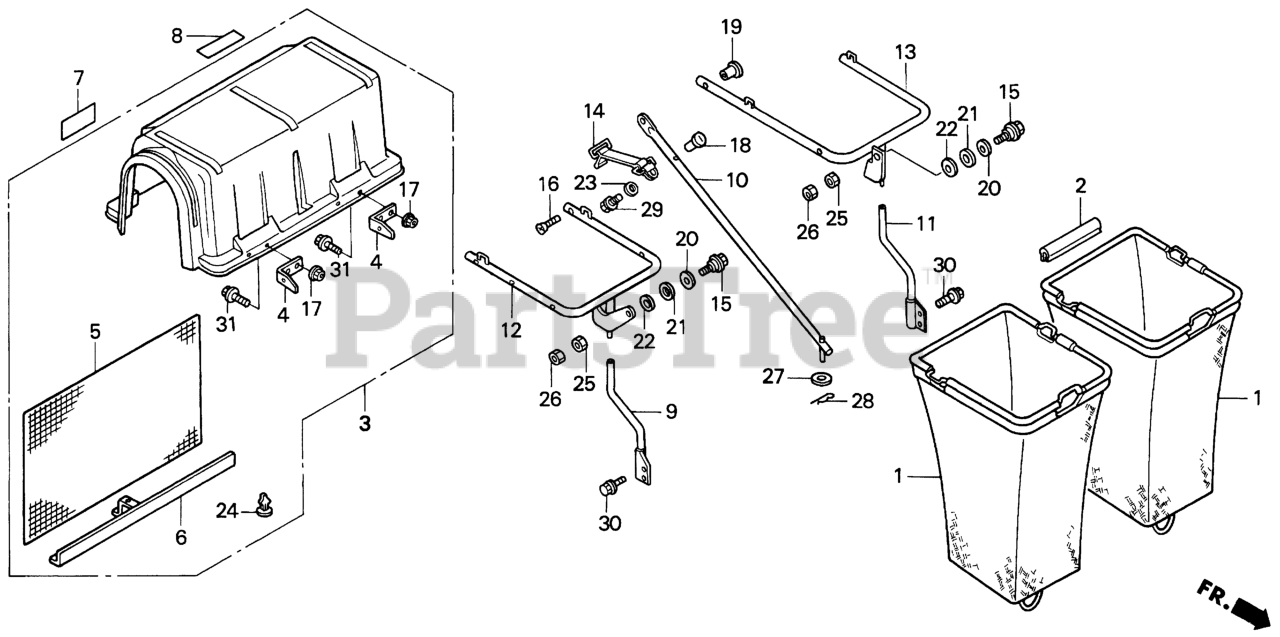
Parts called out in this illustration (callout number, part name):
1	BAG, GRASS
2	CLIP, GRASS BAG TUBE (NOT AVAILABLE)
3	HOPPER ASSY., TOP
4	HINGE, HOPPER TOP
6	STIFFENER, RR. (N/A: SEE ASSEMBLY)
7	LABEL, HOPPER TOP (ENGLISH)
8	LABEL, HOPPER TOP ROOF (ENGLISH)
9	POST, R. SUPPORT
10	BRACE, SUPPORT
11	POST, L. SUPPORT
12	STAY, R. SUPPORT (NOT AVAILABLE)
13	STAY, L. SUPPORT
14	BAND ASSY., HOPPER TOP
15	BOLT, HINGE (10MM)
16	SCREW, FLAT (8X45)
17	NUT, FLANGE (6MM)
18	NUT, PIPE (6MM)
19	NUT, PIPE (8MM)
20	WASHER, THRUST (14MM)
21	WASHER, SPRING (14MM)
22	WASHER (12MM)
23	WASHER (3/8")
24	CLIP, SCREEN
25	NUT, HEX. (10MM) (NOT AVAILABLE)
26	NUT, HEX. (10MM) (SOURCE: VINTAGE PARTS INC.)
27	WASHER, PLAIN (10MM)
28	PIN, LOCK (10MM) Use from Frame SN 2149606 to 2149605.
29	BOLT, FLANGE (6X16) Use from Engine SN 2056820.
30	BOLT, FLANGE (8X20)
31	BOLT, FLANGE (6X18)
